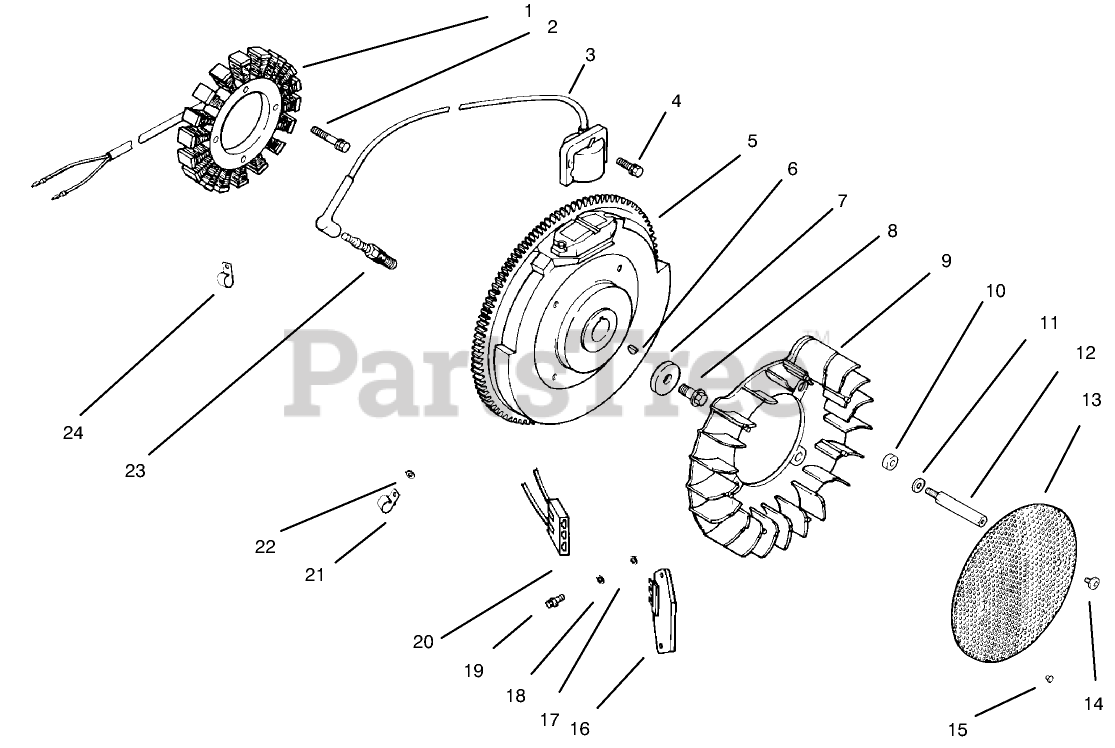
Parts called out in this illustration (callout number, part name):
1	Stator-15 amp
3	Module-Ignition
5	Flywheel
6	KEY (3/16 X 5/8)
7	WASHER-FLAT (13/32)
8	SCREW-FLANGE (M10X1.5X45)
9	Fan
10	Spacer-Fan
11	WASHER-FLAT (1/4)
12	Stud-Grass Screen
13	Screen-Grass
15	Screw-Set (10-24X.25)
16	Rectifier-Regulator, 15 amp
17	WASHER-FLAT (1/4)
18	WASHER-FLAT (.188)
19	SCREW-PHL HD (11-16X.88)
20	Connector (3 contact)
21	CLIP-CABLE
22	WASHER-FLAT (1/4)
23	SPARK PLUG
24	Clip-Cable
